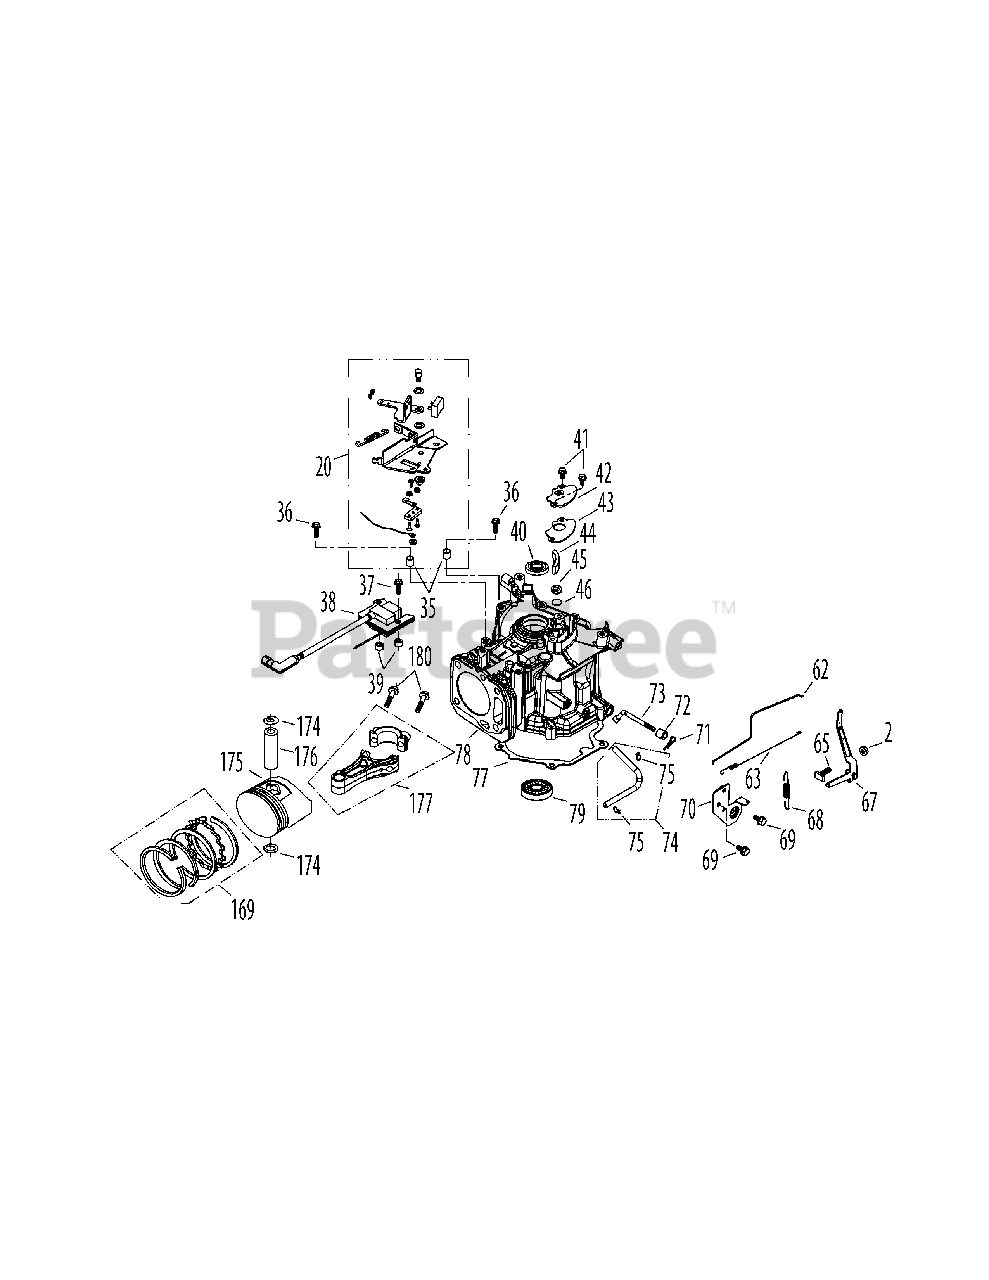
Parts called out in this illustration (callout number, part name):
2	Nut M6 X 10 Mm
20	Brake Assembly
35	Brake Spacer
36	Brake Assy Bolt M6×35
37	Bolt M6x28
38	Ignition Coil Assembly
39	Ignition Coil Spacer
40	Upper Crankshaft Seal
41	Bolt M6×14
42	Breather Cover Plate
43	Breather Gasket
44	Breather Screen
45	Breather Spring
46	Breather Valve
62	Throttle Linkage
63	Throttle Linkage Spring
65	Governor Arm Bolt
67	Governor Arm
68	Governor Spring
69	Bolt M6×12
70	Throttle/Governor Bracket
71	Governor Cotter Pin
72	Governor Seal
73	Governor Arm Shaft
74	Breather Hose Assembly
75	Breather Hose Clamp
77	Crankcase Cover Gasket
78	Crankcase
79	Main Bearing
169	Piston Ring Set
174	Piston Pin Snap Ring
175	Piston
176	Piston Pin
177	Connecting Rod Assembly
180	Connecting Rod Bolt
